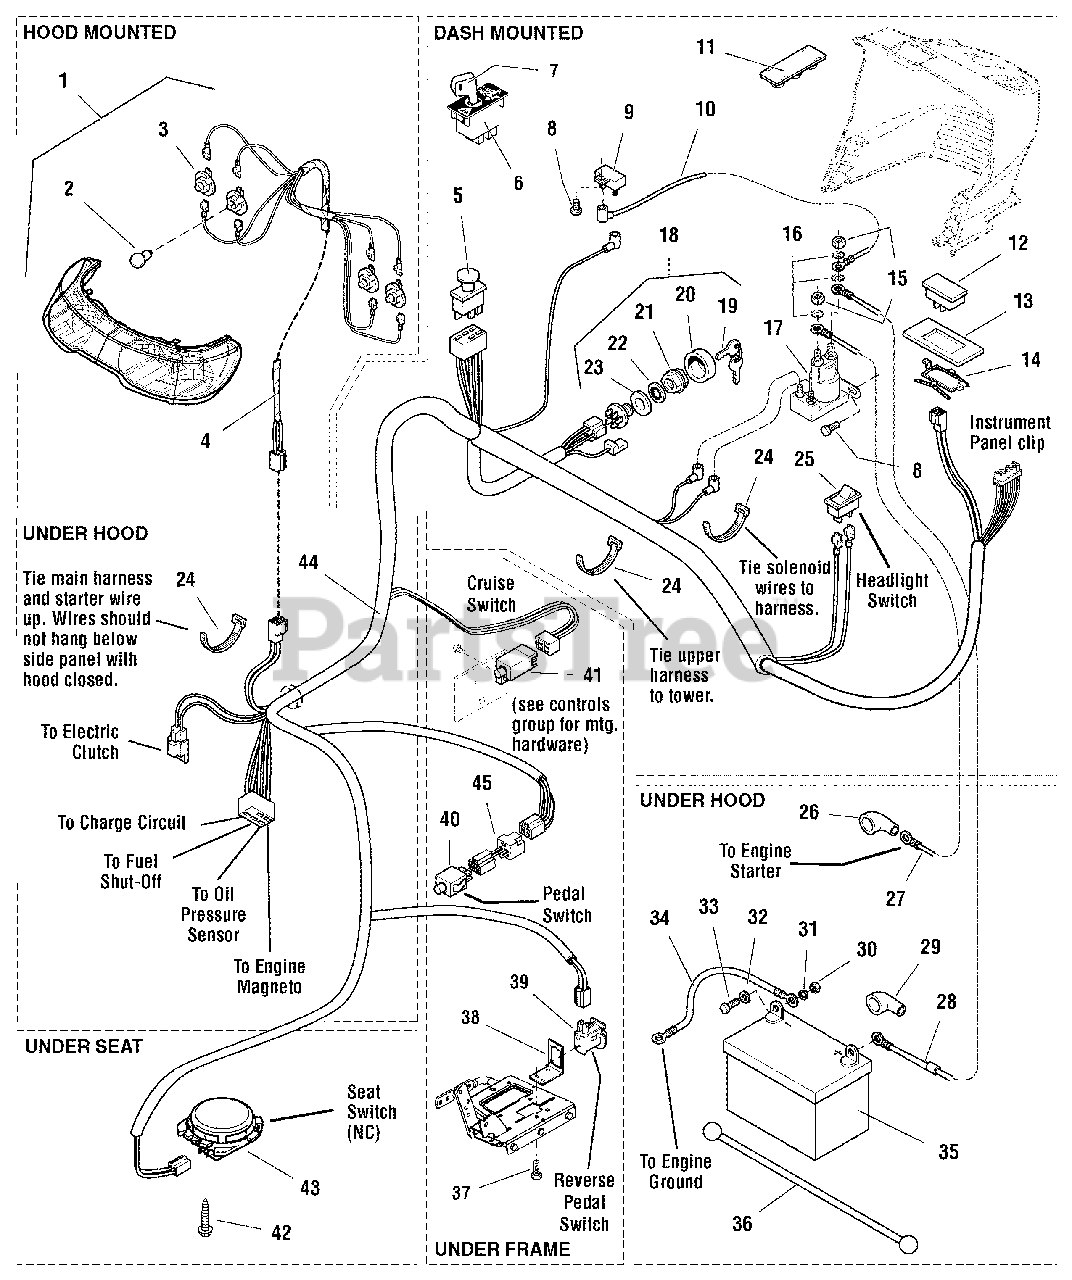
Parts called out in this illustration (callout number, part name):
1	HEADLIGHT ASSEMBLY, 4 Bulb, (Includes Ref. Nos. 2 & 3)
2	BULB, Headlight, 12.8V
3	SOCKET ASSEMBLY, Headlight, Sealed
4	HARNESS, Headlight
5	SWITCH, PTO Push/Pull Symbols
6	SWITCH, RMO Module Only
7	KEY, RMO Module Plastic
8	CAPSCREW, Hex Washer Head Taptite, 1/4-20 x 1/2, Black
9	BREAKER, Circuit, 12 Volt 20 Amps
10	WIRE, 12GA 5-15/16 Long, Red
11	PLUG, Hole, Square
12	HOUR METER
13	PLUG, Dash
14	CLIP, Hour Meter (Service Only)
15	NUT, Hex, 5/16-24
16	LOCKWASHER, External Tooth, 5/16
17	SOLENOID
18	SWITCH ASSEMBLY, Ignition, 6 Pin
19	KEYS, Set of 2
20	COVER, For Ignition Switch, Plastic
21	NUT, Hex Flange, 5/8-32, Ignition Switch
22	LOCKWASHER, Internal Tooth, 5/8, Thin
23	WASHER, Shim
24	TIE, Strap, 7-5/16 Long
25	SWITCH, Headlights , 2 Terminal
26	BOOT, Insulator Cable Terminal, 1-15/16 Long, Red
27	CABLE, #6 x 25" Long, Ring Terminals
28	CABLE, #6 x 8" Long, Ring Terminals
29	BOOT, Insulator Battery Terminal
30	NUT, Hex, 1/4-20
31	LOCKWASHER, 1/4
32	WASHER, 1/4
33	CAPSCREW, Hex Head, 1/4-20 x 3/4
34	CABLE, #6 x 26 Long, Ring Terminal
35	BATTERY, 12 Volt
36	STRAP, Battery, 14 Long, Rubber
37	CAPSCREW, Hex Head Taptite, 1/4-20 x 3/8
38	BRACKET, Switch Mount
39	SWITCH, Push Button, NO, Black
40	SWITCH, Push Button, Foot Pedal
41	SWITCH, Cruise Control, Grey, NO
42	CAPSCREW, Hex Washer Head Plastite, 1/4 x 1/2
43	SWITCH, Seat, Grey, NC
44	HARNESS, Wiring
45	WIRING ASSEMBLY, All Conditions Shutdown
